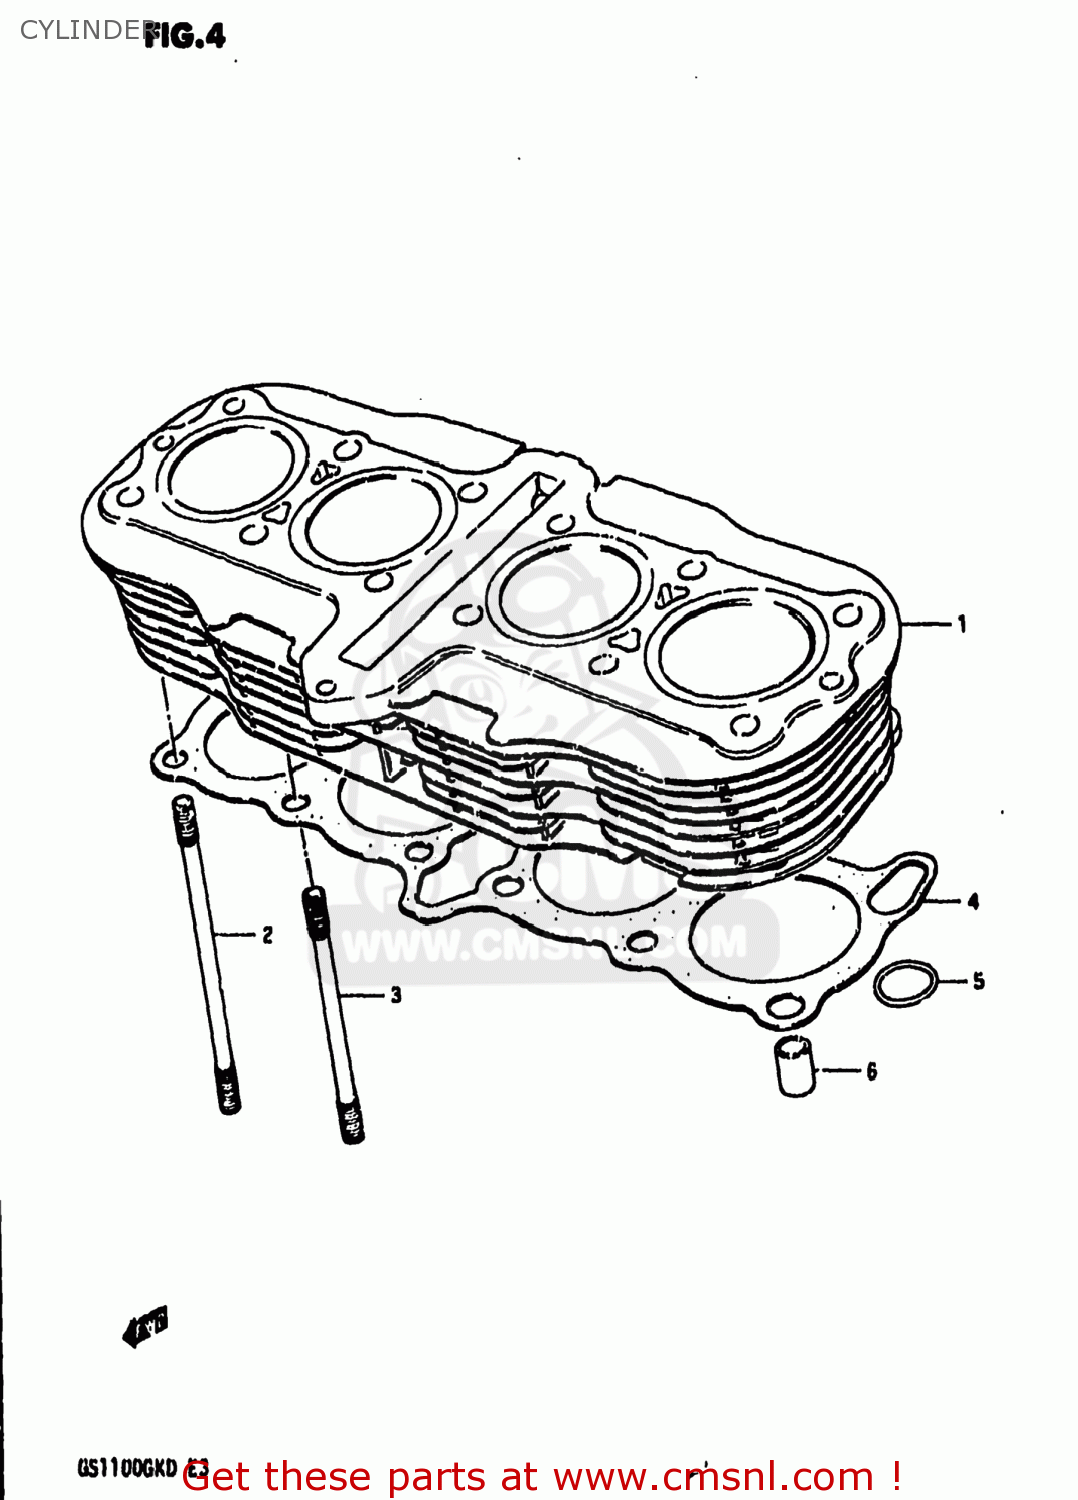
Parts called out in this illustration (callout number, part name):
1	CYLINDER
2	BOLT,STUD
3	STUD
4	GASKET,CYLINDER (MCA)
5	O RING(D:3.5)
6	PIN
